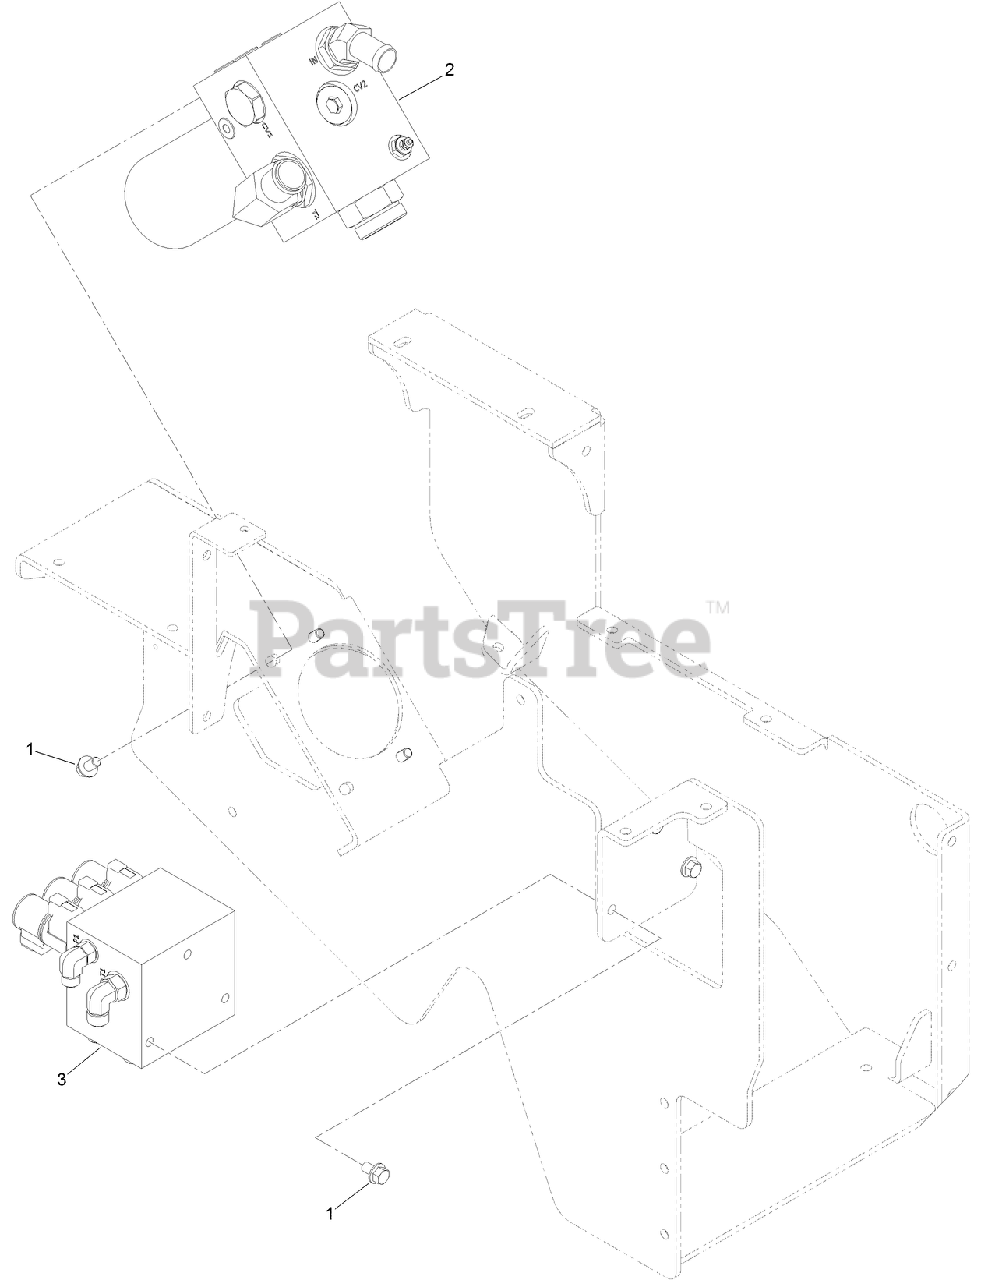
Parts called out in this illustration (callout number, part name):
1	SCREW-HHF
2	RETURN MANIFOLD ASM
3	SETUP MANIFOLD ASM
